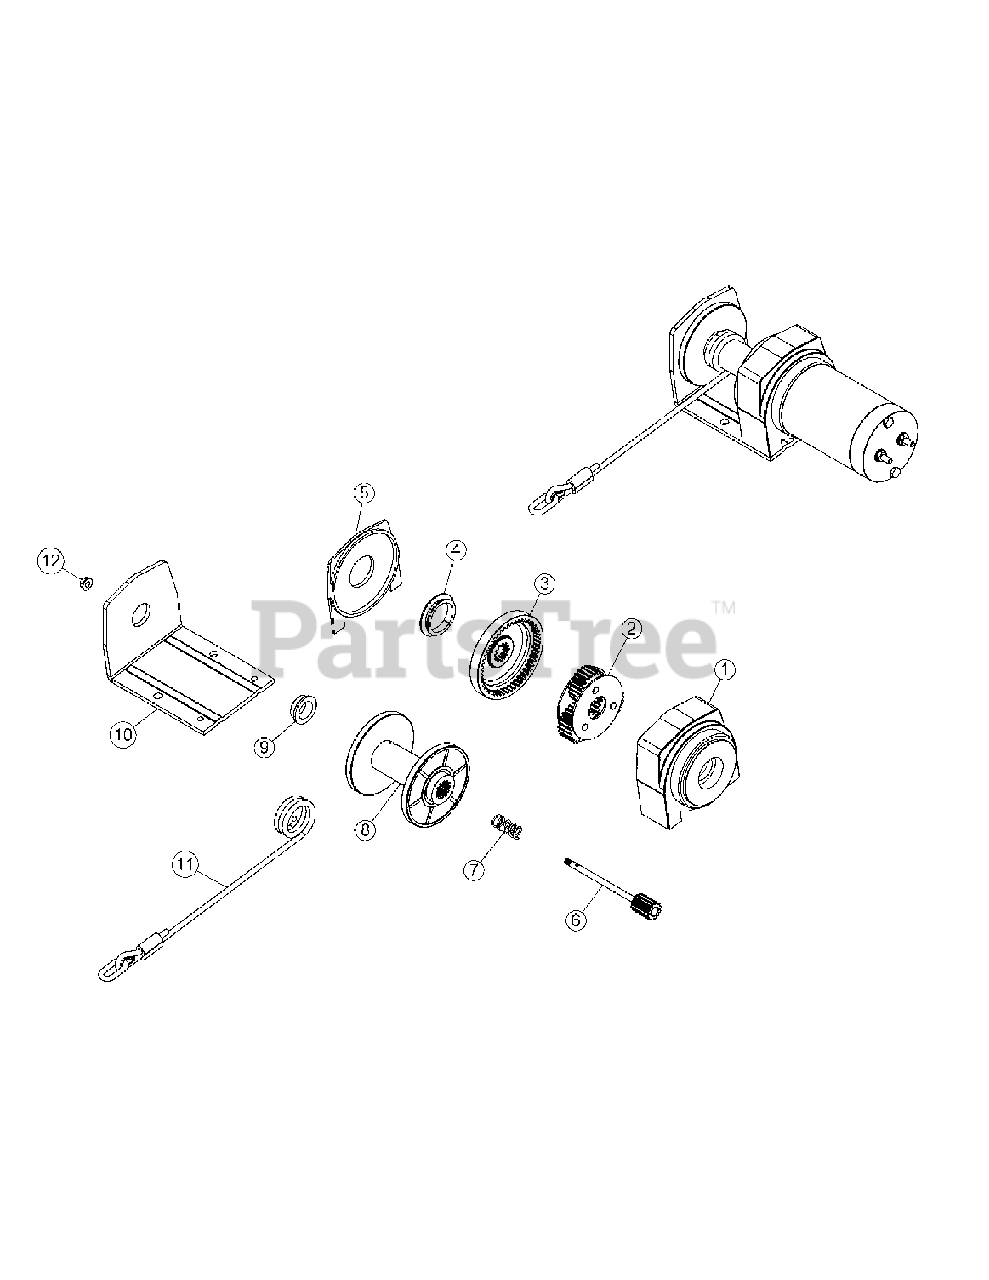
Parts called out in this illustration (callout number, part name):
1	Reduction box
2	Planetary gear
3	Inner gear
4	Drum support bushing
5	Drum support plate
6	Spline shaft
10	Base plate assembly
11	Winch cable
12	Flange nut M6 x 1.00
